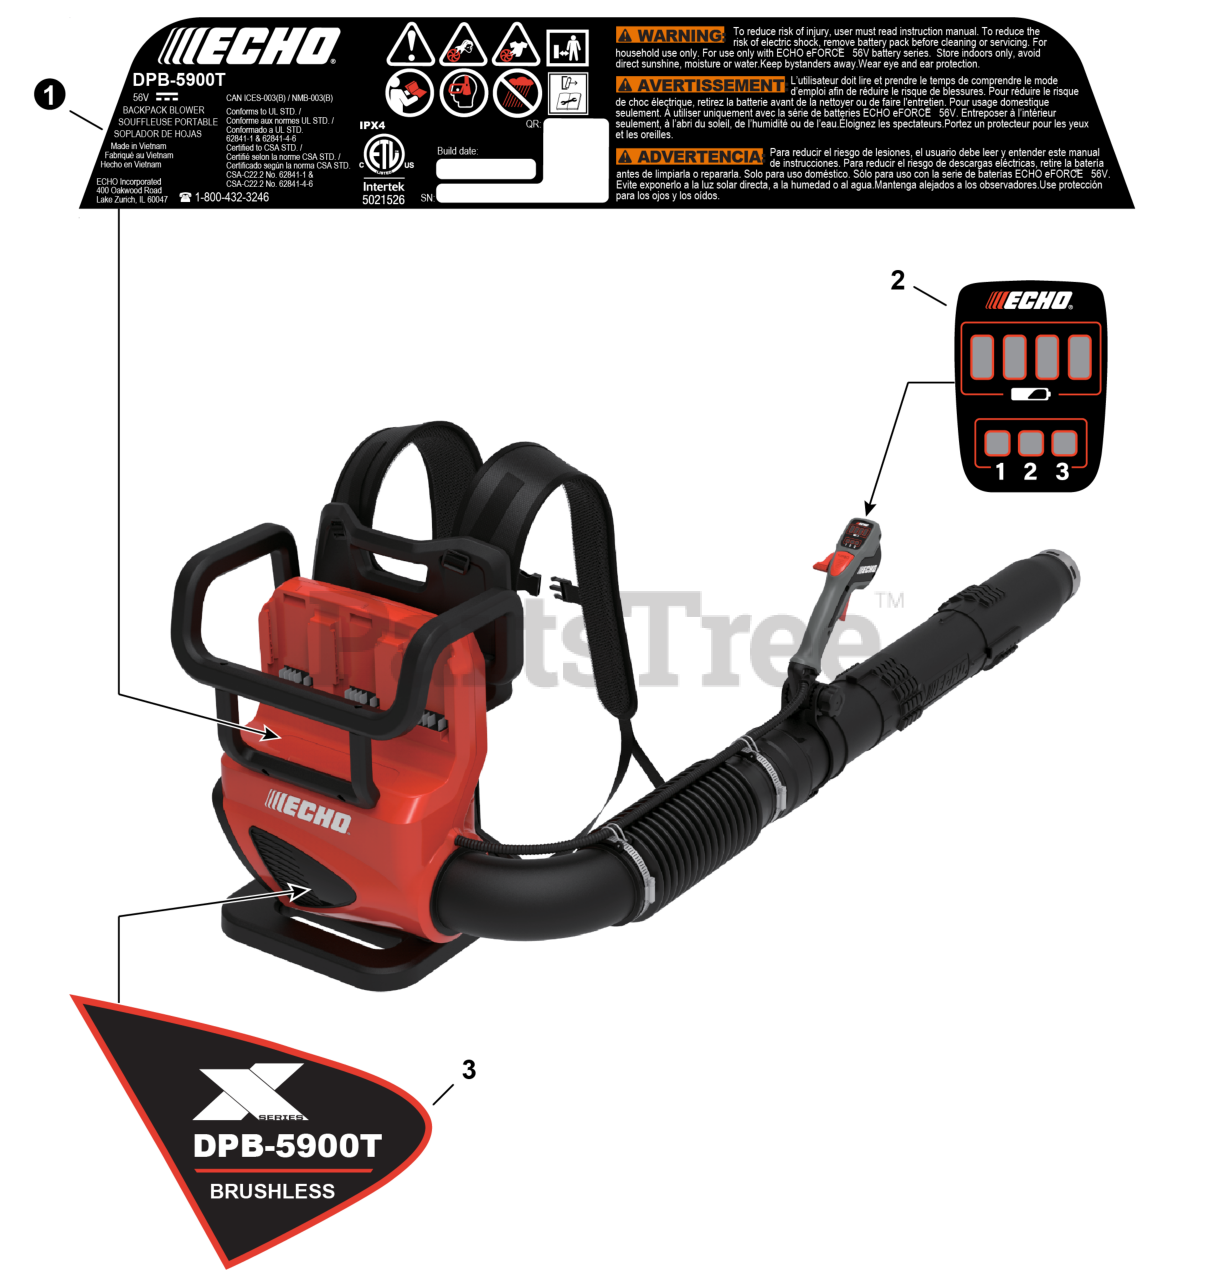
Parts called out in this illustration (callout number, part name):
1	LABEL, WARNING/SERIAL
2	LABEL, LED
3	LABEL, MODEL
